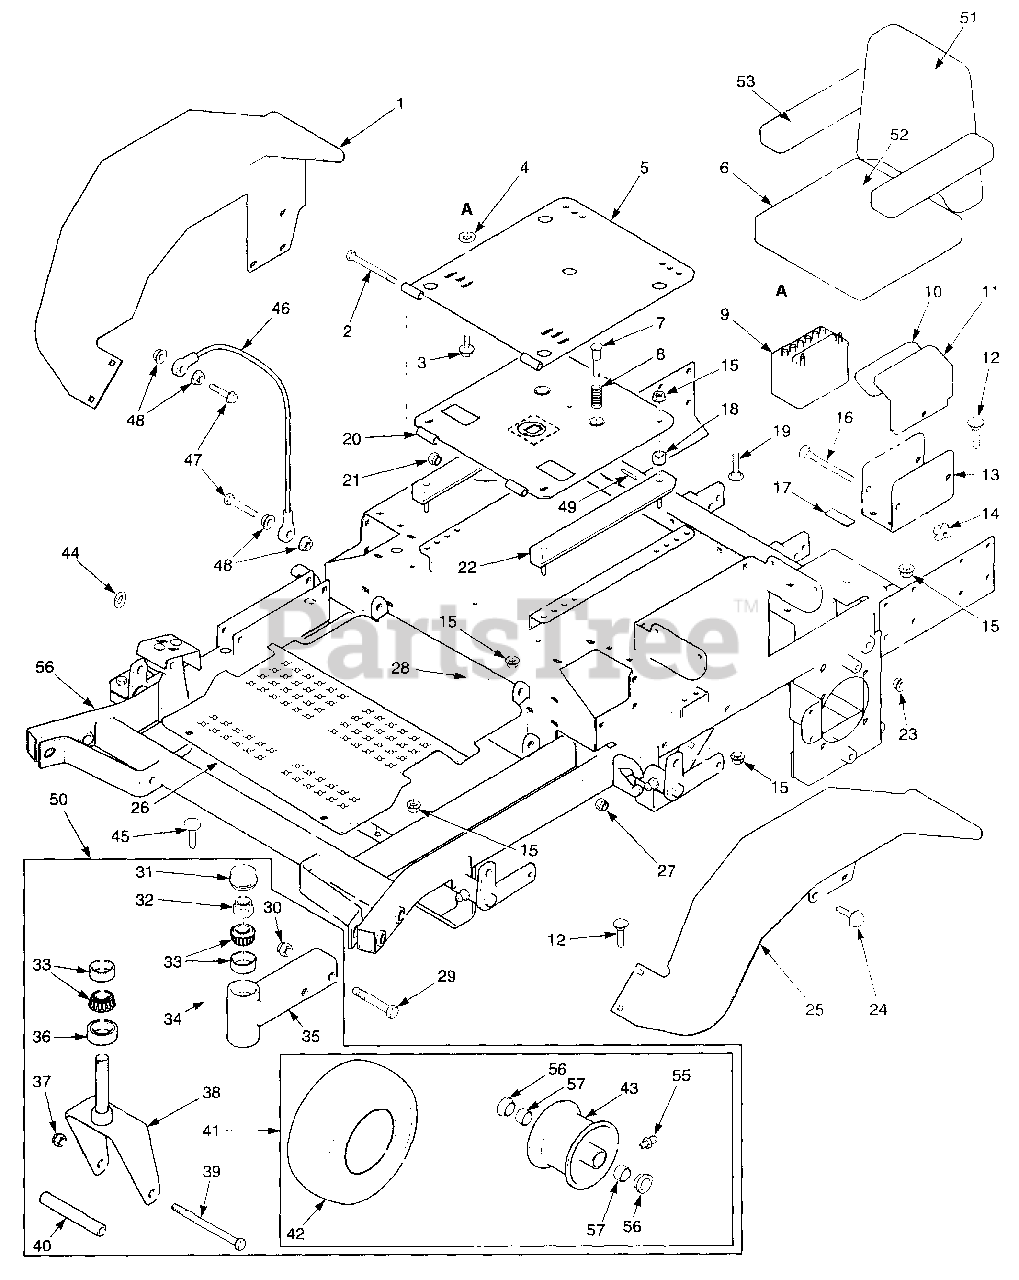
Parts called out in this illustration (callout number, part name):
1	Fender Weldment, RH
2	Bolt, Hex Head 5/16-18 x 3-1/2"
3	Screw, Hex Serrated Flange 5/16-18 x 3/4"
4	Flatwasher, 3/8" (.406 x 1.50 x .179)
5	Seat Plate Weldment, Upper
7	Pin Retainer, Spring
8	Spring, Seat
9	Battery
10	Pad, Battery Cover
11	Cover, Battery
12	Bolt, Carriage 5/16-18 x 3/4"
13	Plate, Battery Box
14	Wing Nut, 1/4-20 x 3/4"
15	Nut, Hex Serrated Flange 5/16-18
16	Bolt, Carriage 1/4-20 x 6"
17	Rubber Pad
18	Spacer
19	Bolt, Carriage 5/16-18 x 1"
20	Seat Plate Weldment, Lower
21	Nut, Hex Elastic Stop 5/16-18
22	Seat Adjustment, Track Set
23	Nut, Hex Serrated Flange 3/8-16
24	Screw, Hex Serrated Flange 3/8-16 x 1"
25	Fender Weldment, LH
26	Foot Plate
27	Nut, Hex Elastic Stop 3/8-16
28	Bolt, Hex Head 3/8-16 x 1-1/4"
29	Bolt, Hex Head 5/8-11 x 4"
30	Nut, Hex Elastic Stop 5/8-11
31	Cap, Grease
32	Nut, Hex Elastic Stop 1.0-14
33	Bearing W/Race
34	Plug, 1/4-28 THD Form
35	Extension Weldment, Caster 52" Deck (LH & RH)
36	Seal, 2.00 OD. x 1.625 Bore
37	Nut, Hex Elastic Stop 1/2-13
38	Yoke Weldment, Caster
39	Bolt, Hex Head 1/2-13 x 7-1/2"
40	Sleeve
41	Wheel Assy
43	Rim Assembly
44	Washer, 3/8"
45	Bumper, Rubber
46	Cable, Seat Stop
47	Bolt, Hex Head 1/4-20 x 1-1/4"
48	Nut, Hex Serrated Flange 1/4-20
49	Roll Pin, Spring 5/32 x 3/4"
50	Caster Wheel Assy 52"B (RH) & 61"B (LH & RH)
51	Back Cushion
52	Seat Cushion
53	Arm Pad, RH
55	Grease Fitting
56	Bearing, Oilite
57	Roller Bearing
